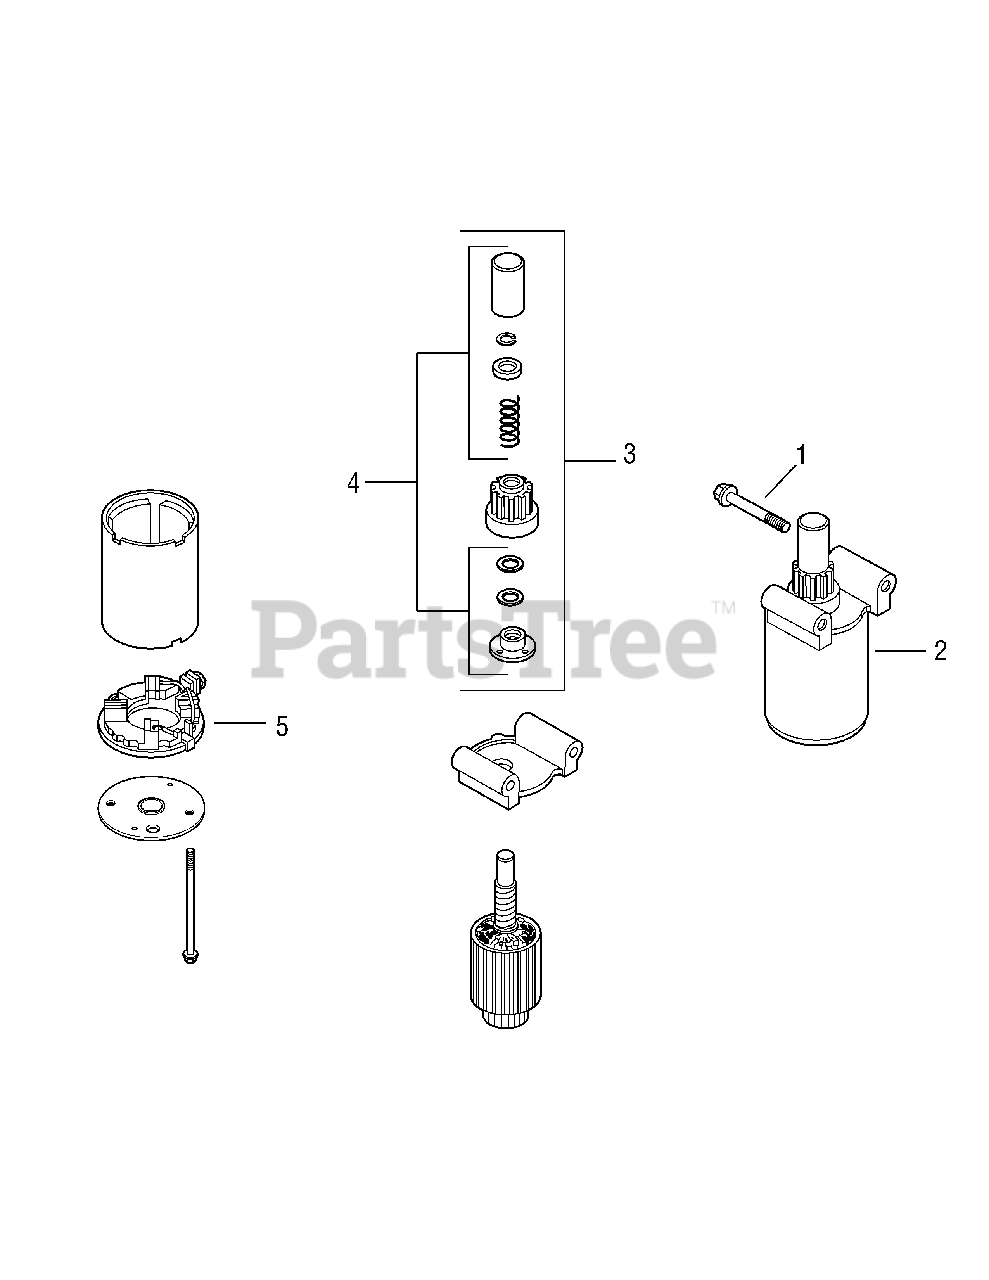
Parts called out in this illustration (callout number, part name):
1	Hex Flange Screw, M8 x 1.25 x 70
2	Starter Assembly (Inc. 3-5)
4	Drive Parts Kit
5	End Cap Commutator
